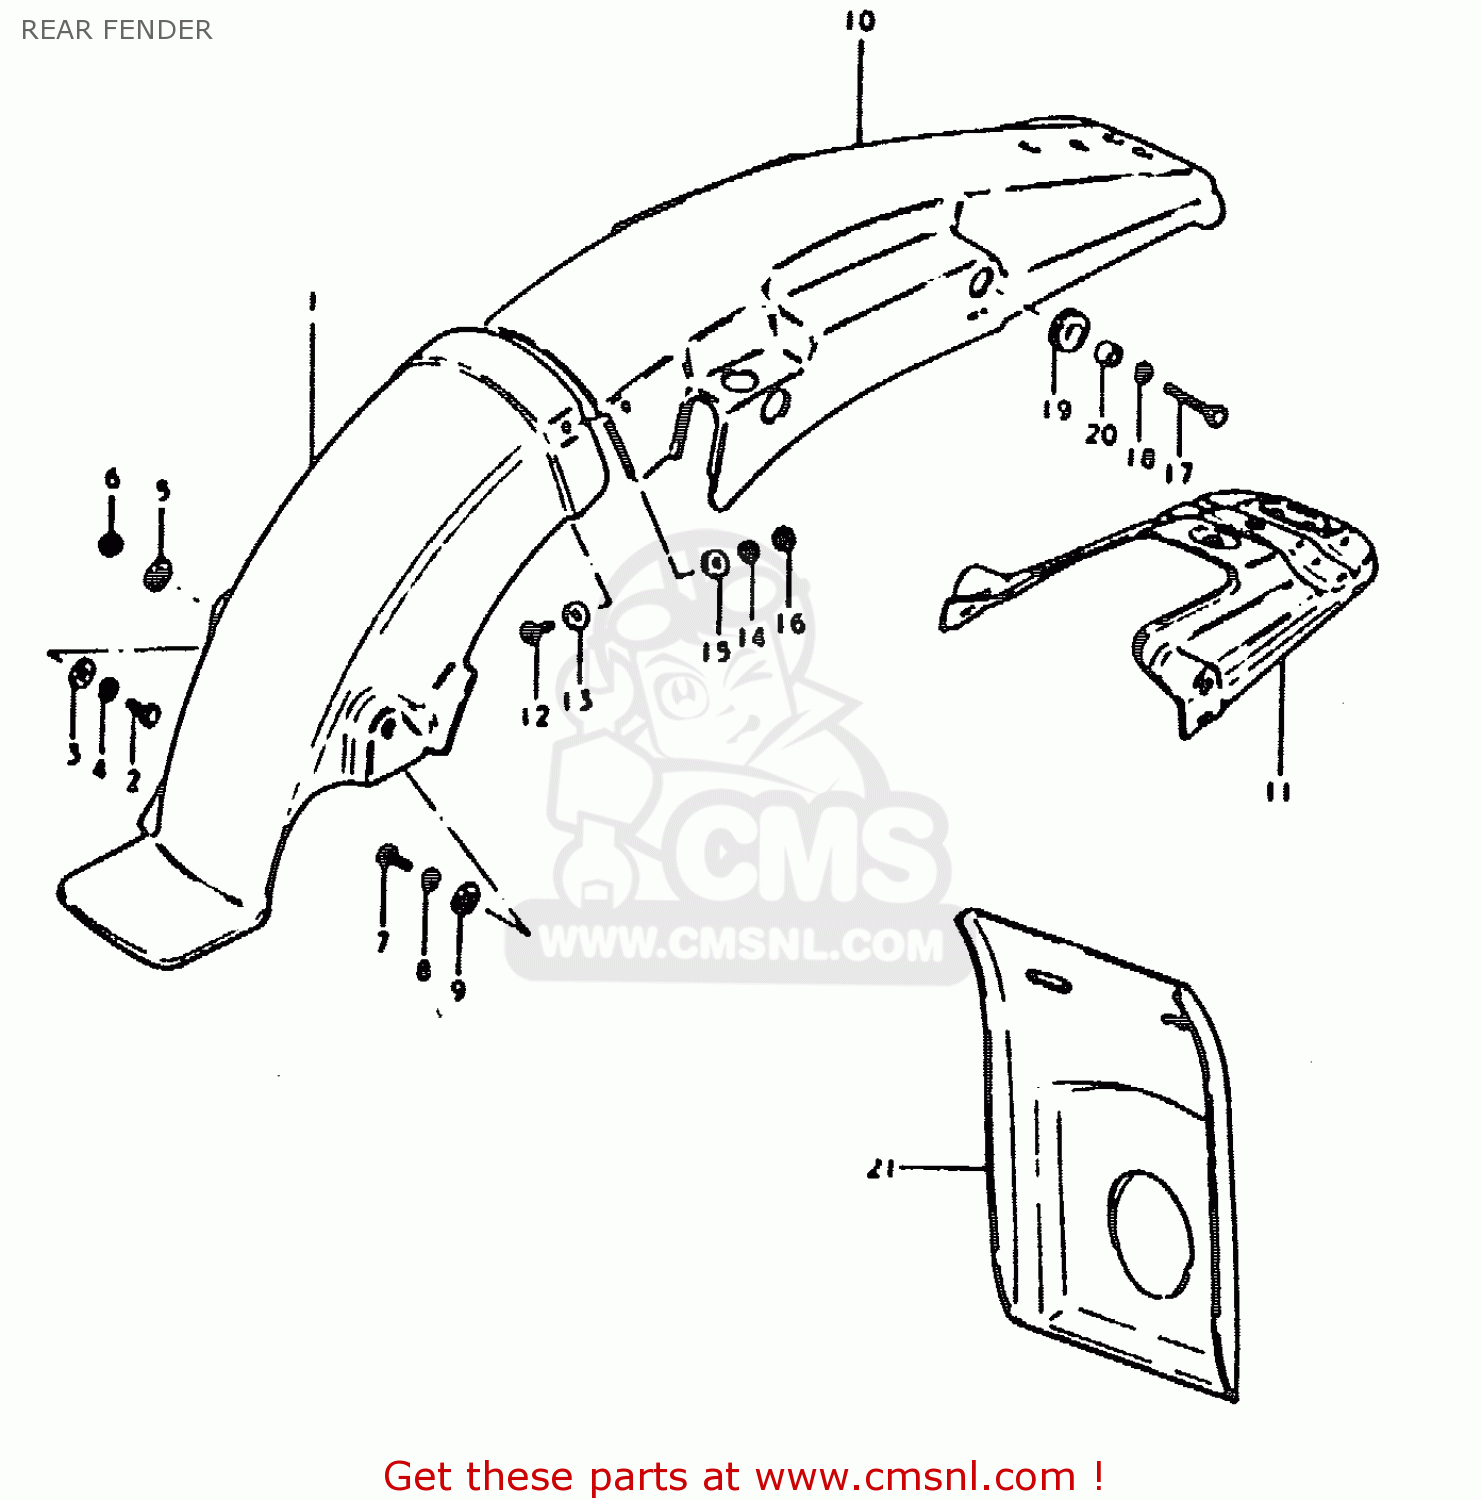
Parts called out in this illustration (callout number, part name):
1	FENDER,REAR
2	BOLT, UPPER
3	WASHER
4	LOCK WASHER
5	WASHER
6	NUT
7	BOLT
8	LOCK WASHER
9	WASHER
10	FENDER, REAR
11	REINFORCEMENT,RR FENDER
12	BOLT
13	WASHER (5.5X16X1.2)
14	LOCK WASHER
15	WASHER(5.2X16X1)
16	NUT
17	BOLT (8X30)
18	LOCK WASHER
19	CUSHION
20	SPACER (8.2X12X7.5)
21	FLAP,RR FENDER MUD
